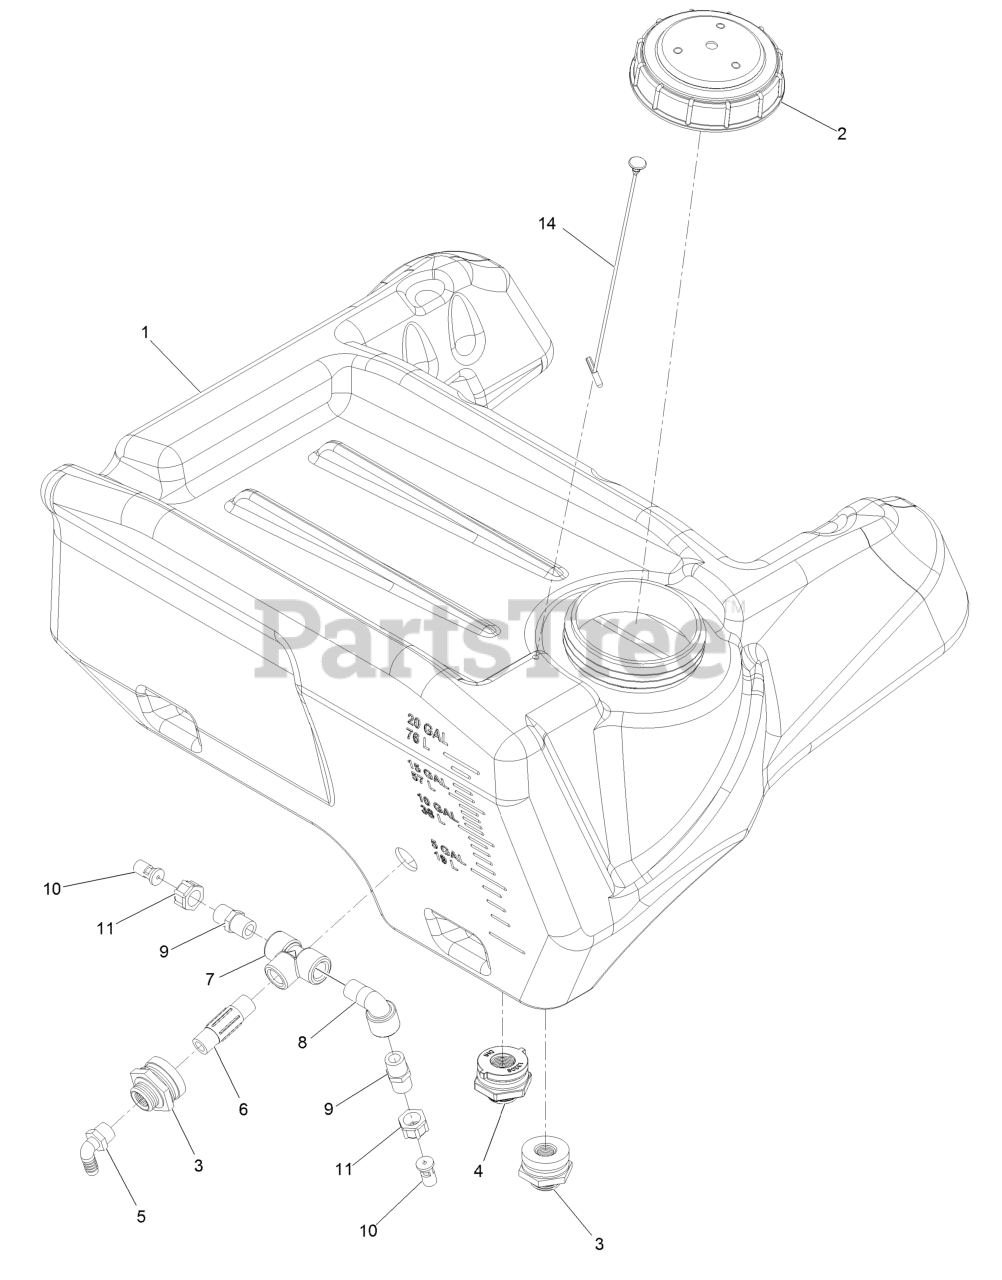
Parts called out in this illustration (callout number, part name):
1	Tank-Sprayer
2	CAP-WATER, 5 INCH VENT
3	FITTING-BULKHEAD
4	FITTING-BULKHEAD
5	ELBOW-90 DEG
8	ELBOW-90 DEG
9	NIPPLE-SHORT
10	NOZZLE-AGITATION
14	LANYARD-CAP, SELF ANCHORI
